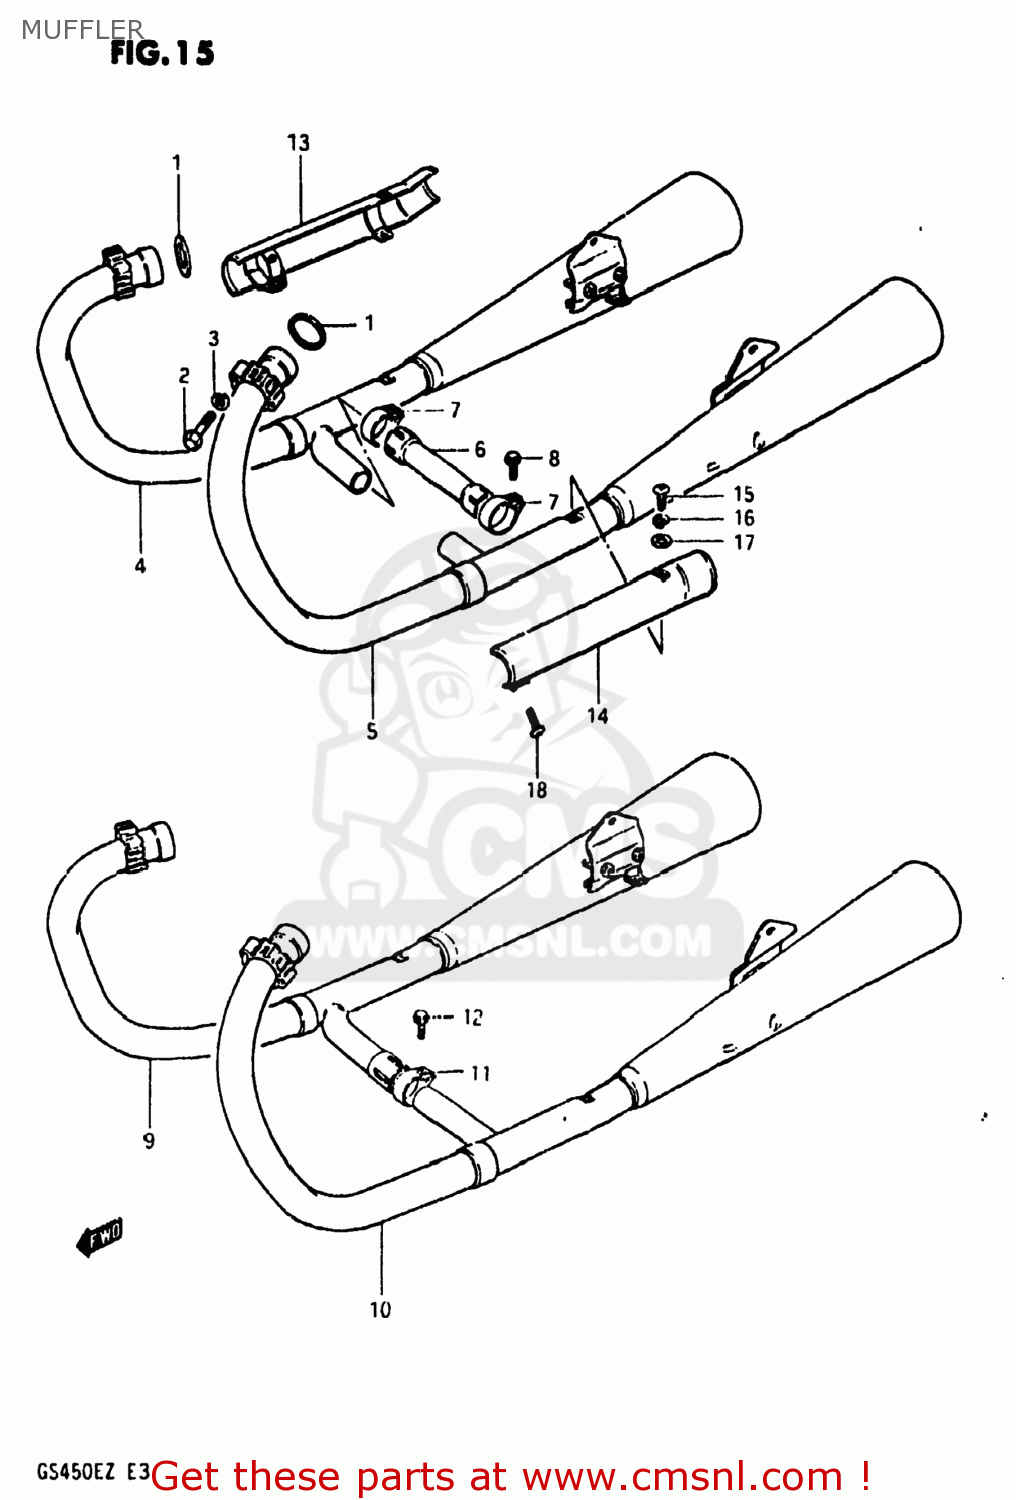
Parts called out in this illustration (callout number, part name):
1	GASKET,EXHAUST PIPE (NAS)
2	BOLT
3	LOCK WASHER
4	MUFFLER ASSEMBLY
5	MUFFLER ASSEMBLY
6	PIPE,EXHAUST COUPLER
7	CLAMP
8	BOLT
9	MUFFLER ASSEMBLY
10	MUFFLER ASSEMBLY
11	CLAMP
12	BOLT
13	COVER,MUFFLER
14	COVER,MUFFLER
15	SCREW
16	LOCK WASHER
17	WASHER
18	SCREW
